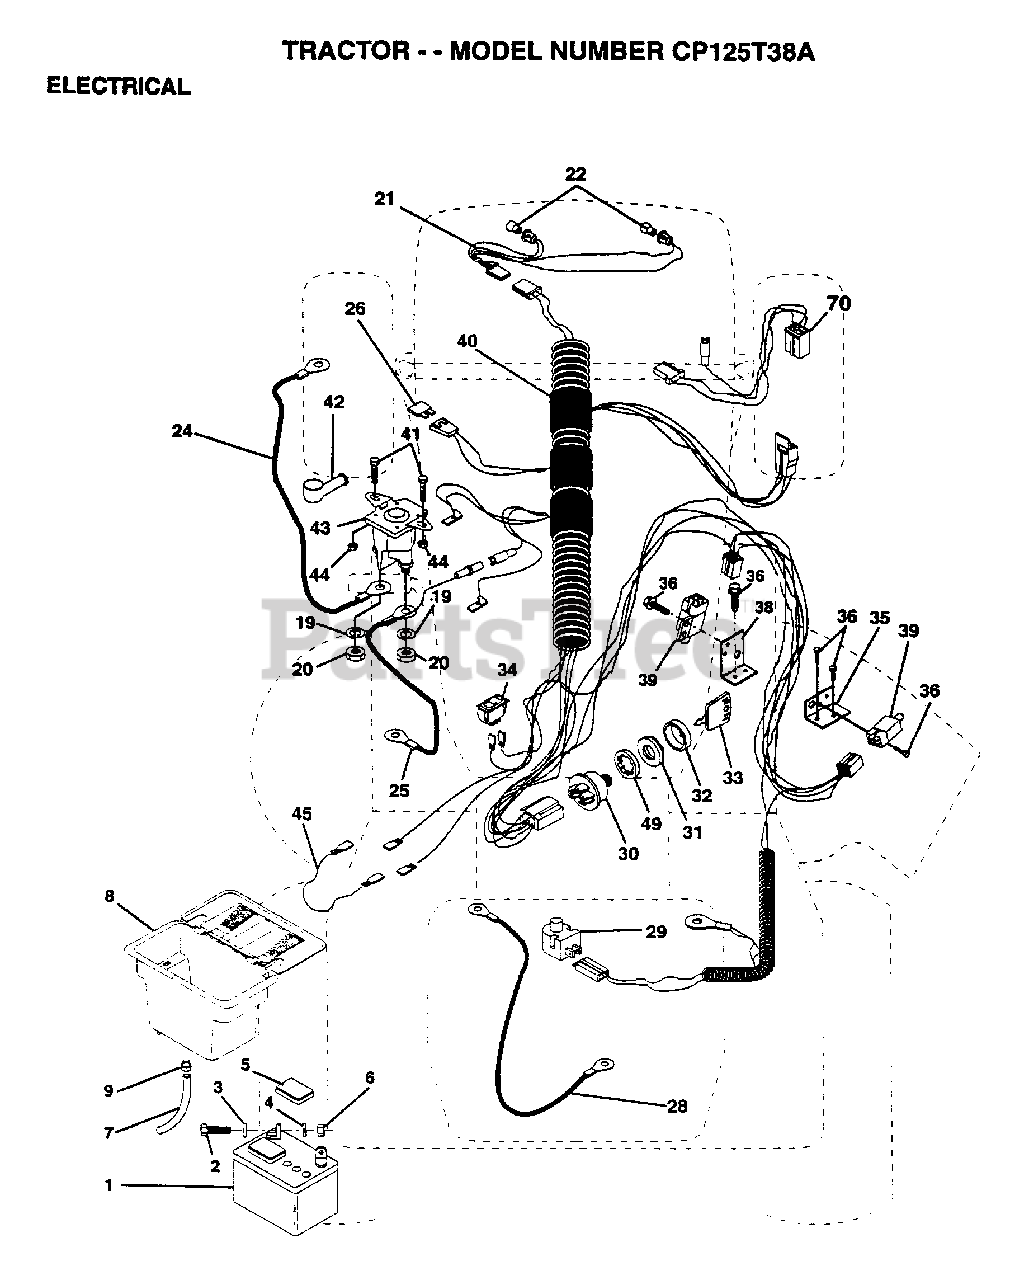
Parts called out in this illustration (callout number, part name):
2	BOLT LT
3	WASHER
4	LOCKWASHER
5	"CAP,BATTERY "
7	TUBE T
9	HOSE CLAMP T
20	NUT
21	"HARNESS,LIGHT SOC"
22	HEADLAMP BULB
24	"CABLE T, BATTERY"
25	CABLE.BTRY.6GA.RD
26	FUSE HYT
28	CABLE T
29	SWITCH SEAT
32	COVER KEY SWITCH
33	KEY STEEL DELTA
34	SWITCH LT
35	BRACKET LT
36	SCREW
38	BRACKET SWITCH IN
39	SWITCH INTERLOCKT
40	HARNESS.IGN.DASH.
41	BOLT.HX.1/4-20
44	NUT
45	ADAPTER AMMETER
49	LOCKWASHER
70	HARNESS ENG DUAL
